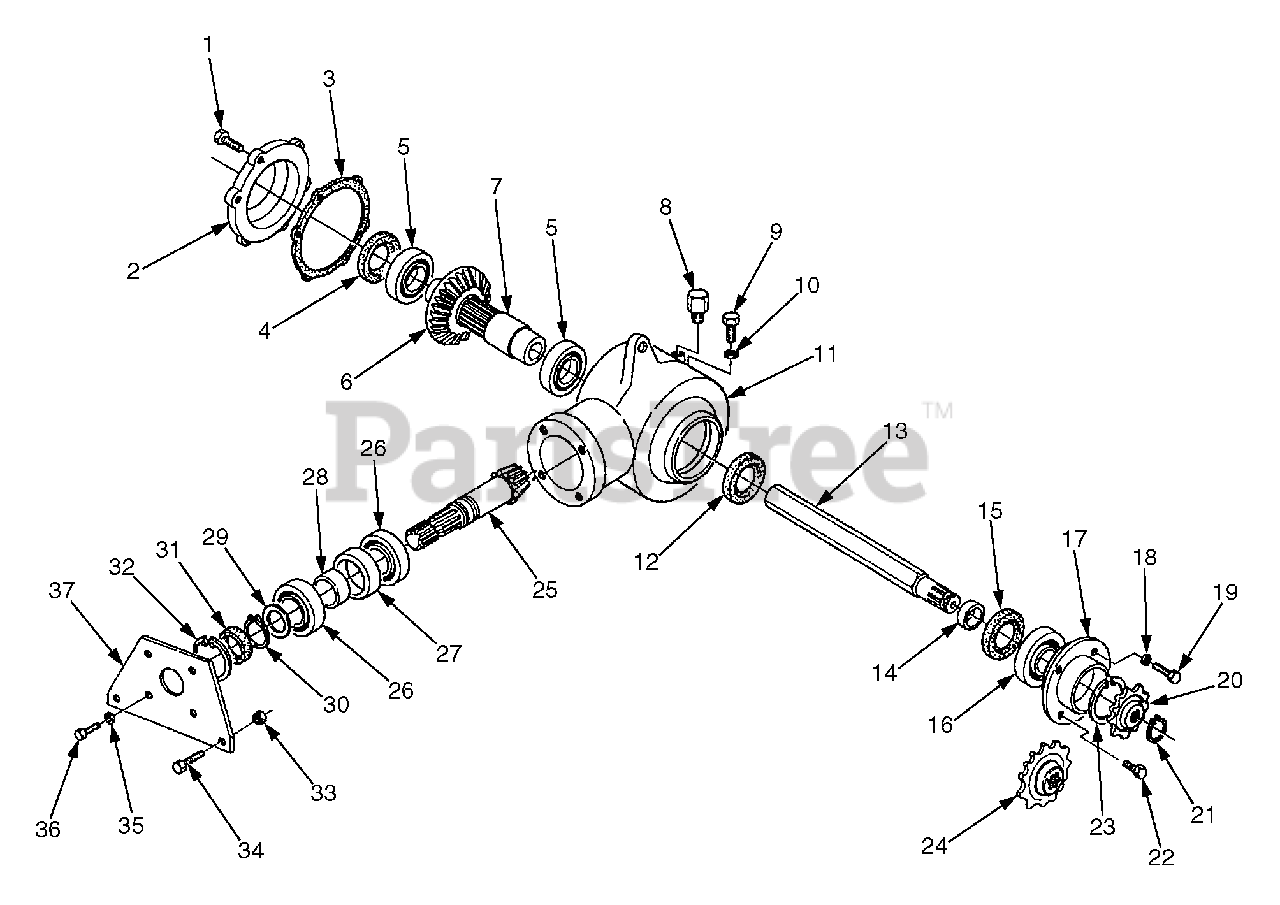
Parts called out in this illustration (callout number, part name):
1	Bolt, 10 x 20
7	Shaft Coupling
8	Breather Cap
9	Bolt, 16 x 50
10	Flat Washer M16
13	Hexagonal Shaft
17	Top Shaft Flange
18	Lock Washer M10
19	Bolt, 10 x 40
22	Bolt, 10 x 25
25	Pinion Gear
29	Spacer Washer
34	Bolt, 14 x 40
35	Flat Washer, M12
36	Bolt, 12 x 30
37	Cover, Gearbox Front
